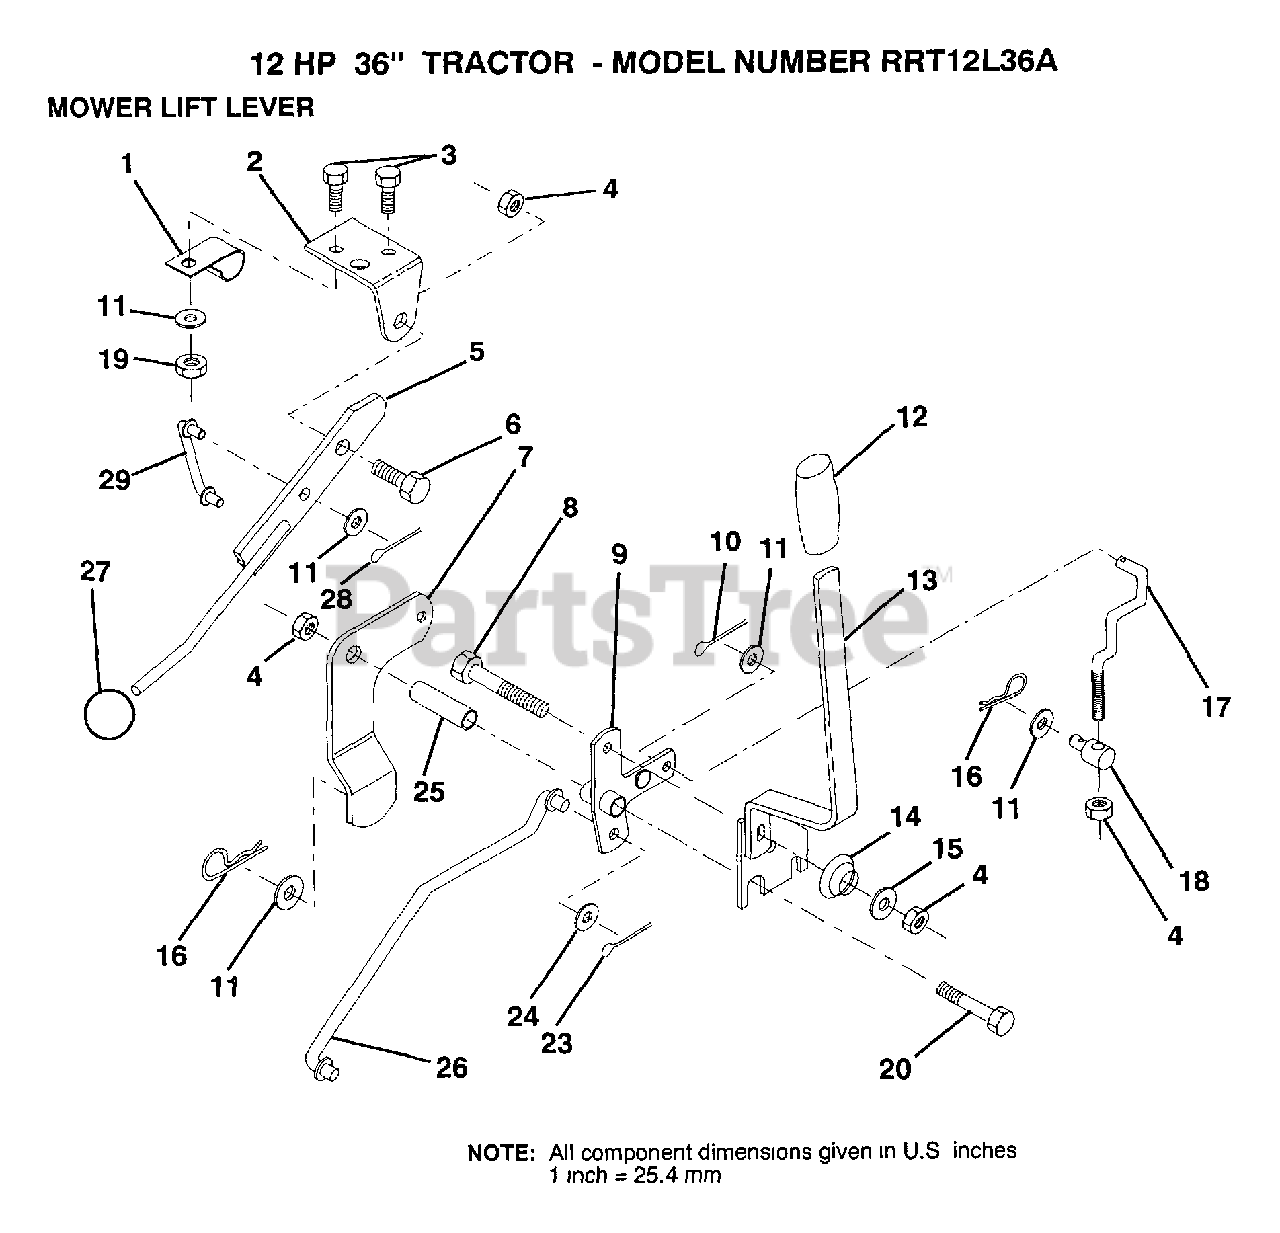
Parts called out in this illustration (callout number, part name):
1	"CLIP,INSULATOR"
2	BRKT CLUTCH
3	BOLT
5	CLUTCH LEVER AS
6	"BOLT, SHOULDER LT"
7	MWR CLUTCH ARM AS
8	BOLT
9	"BELLCRANK,LIFT"
10	COTTER PIN
11	WASHER
13	"HDLE,LIFT T"
14	SPRING COMPRESSIO
15	WASHER T
16	SPRING.RETAINER
17	"LINK,LIFT FRT"
18	TRUNION
20	BOLT
23	PIN COTTER 1/8
25	TUBE SPACER
26	"ROD,MOWER LIFT "
27	KNOB T(3/8 HOLE)
29	CLUTCH LINK
